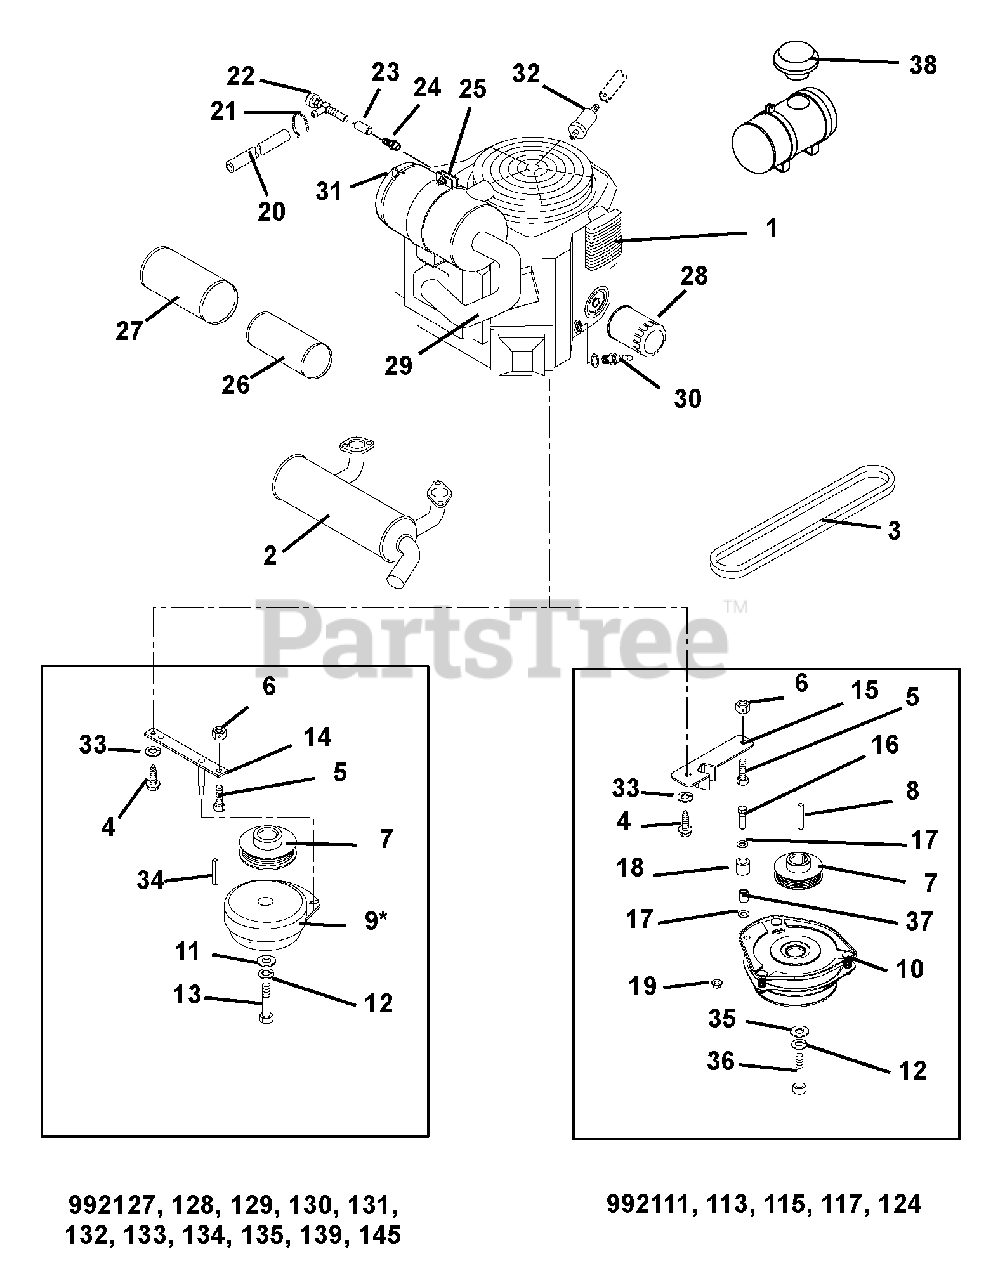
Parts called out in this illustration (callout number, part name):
1	Engine, 25 HP Kawasaki (FH721V) (992111, 115, 127, 128, 131, 132)
1	Engine, 26hp Liquid Cooled Kawasaki (FD731V) (992113, 117, 124, 130, 134, 135, 139)
1	Engine, 27hp Kohler (CV740S) (992129, 133, 145)
2	Muffler, Kawasaki (992111, 115, 127, 128, 131, 132)
2	Muffler, Kawasaki Liquid Cooled (992113, 117, 124, 130, 134, 135, 139)
2	Muffler, Kohler Twin (992129, 133, 145)
3	Belt, Poly-V
4	Screw, Tapping Hex Washer Head .38-16 x 1.00 (992111, 115, 127, 128, 129, 131, 132, 133,145)
5	Bolt, Hex M8-1.25 x 25 Grade 8 (992113, 117, 124, 130, 134, 135, 139)
5	Bolt, Hex .31-18 x 1.75 Grade 5 (992111, 115, 127, 128, 129, 131, 132, 133, 145)
6	Nut, Locking Top Flange .31-18
7	Sheave, Poly V 1.127 x 3.25-XDZ
8	Key-Square .25 x 3.50 x .25 SAE
9	Clutch, Electric (992127, 128, 129, 130, 131, 132, 133, 134, 135, 139, 145)
10	Clutch, Electric (992111, 113, 115, 117, 124)
11	Washer, Flat Steel .515 x 1.625 x .250
12	Washer, Locking .44 x .109
13	Bolt, Hex .44-20 x 3.00 Grade 5
14	Anchor, Clutch (992127, 128, 129, 130, 131, 132, 133, 134, 135, 139, 145)
15	Anchor Clutch (992111, 113, 115, 117, 124)
16	Bolt-Hex .38-16 x 1.50 Grade 5
17	Washer-Flat-Steel .406 x .812 x .065
18	Bumper,Rubber .62 x 1.0 x .88 LG
19	Nut-Locking-Top-Flange .38-16
20	Gas Line, Bulk .25 I.D.
21	Cable Tie LG 5-1/2
22	Drain, 1/2" Drain
23	Adapter, .38 NPTF
25	Bracket, Air Cleaner Mount
26	Element, Inner Safety
27	Element, Outer Primary
28	Oil Filter (992111, 115, 127, 128, 131, 132)
28	Oil Filter (992113, 117, 124, 130, 134, 135, 139)
28	Oil Filter (992129, 133, 145)
29	Hose, Air Intake (992129, 133, 145)
30	Spark Plug (992111, 115, 127, 128, 131, 132)
30	Spark Plug (992113, 117, 124, 130, 134, 135, 139)
30	Spark Plug (992129, 133, 145)
31	Assembly, Air Cleaner
32	Fuel Filter (992111, 115, 127, 128, 131, 132)
32	Fuel Filter (992113, 117, 124, 130, 134, 135, 139)
32	Fuel Filter (992129, 133, 145)
33	Washer, Lock .31 x .078
34	Key, Square .25 x 1 x 0.25
35	Washer, Flat Steel .469 x 2 x .25
36	Bolt, Hex .44-20 x 2.50 Grade 5
37	Bushing, .407 x .625 x .813
38	Cap, Air Cleaner Intake (992113, 117, 124, 130, 134, 135, 139)
